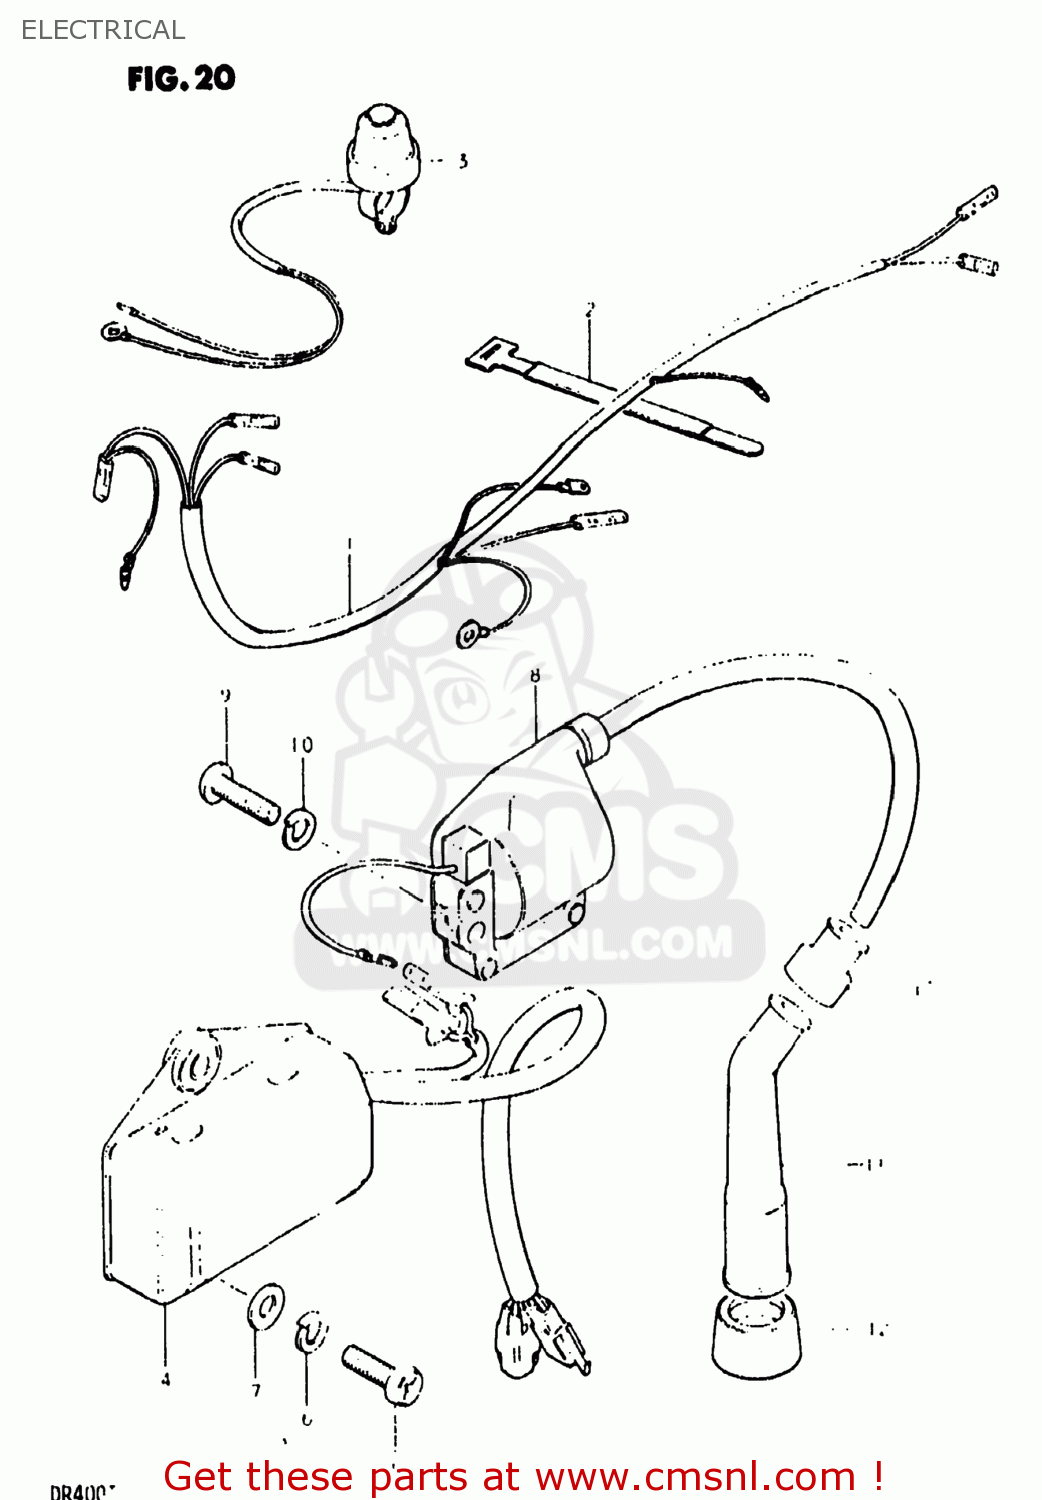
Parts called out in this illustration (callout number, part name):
1	HARNESS,WIRING
2	CLAMP
3	SWITCH ASSEMBLY
4	CDI UNIT
5	SCREW
6	LOCK WASHER
7	WASHER
8	COIL ASSEMBLY,IGNITION
9	SCREW 5X20
10	LOCK WASHER
11	CAP ASSY,SPARK PLUG
12	SEAL,SPARK PLUG
13	SEAL,SPARK PLU
